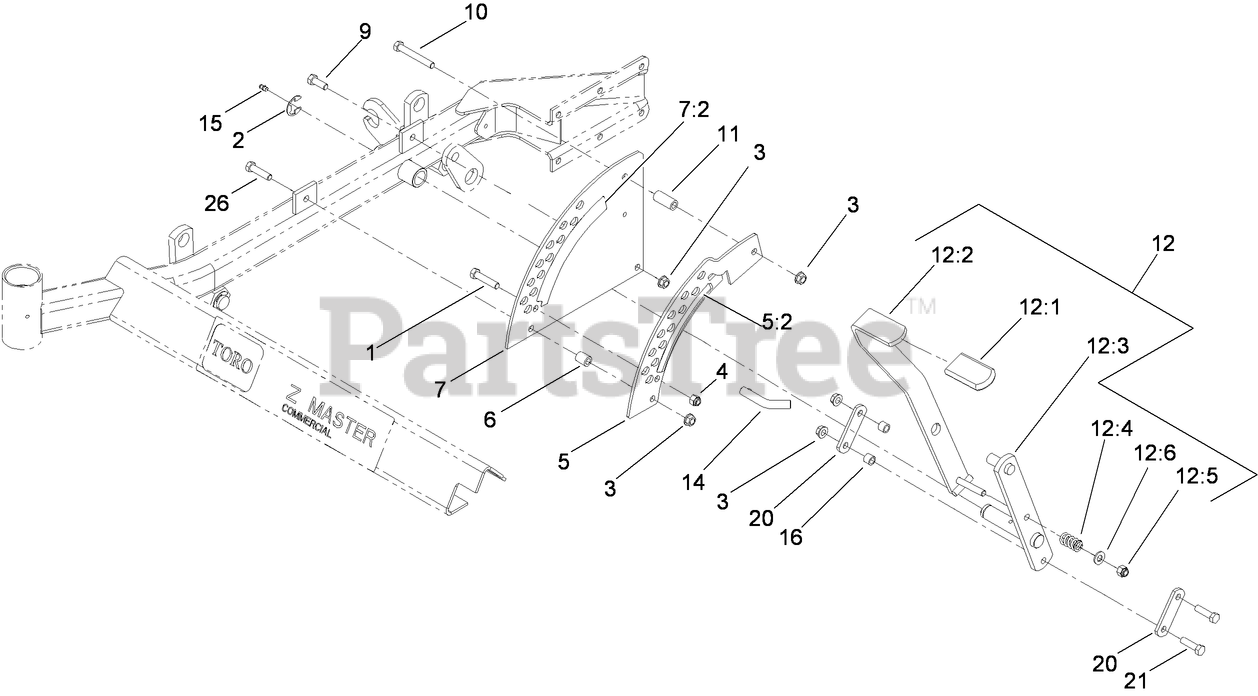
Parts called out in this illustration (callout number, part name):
1	SCREW-HH
2	RING-RETAINING, EXT
3	NUT-HHF, WHIZ
4	NUT-LOCK, NI
5	PLATE-HOC, INNER
5:2	DECAL-DECK HEIGHT, INNER
6	BUSHING-LEVER, LIFT
7	PLATE-HOC, OUTER
7:2	DECAL-DECK HEIGHT, OUTER
9	SCREW-HH
10	SCREW-HH
11	BUSHING-LEVER, LIFT
12	DECK LIFT HANDLE ASM
12:1	GRIP-LEVER, LIFT
12:2	HANDLE-LIFT
12:3	LIFT ARM ASM
12:4	SPRING-COMPRESSION
12:5	NUT-LOCK, NI
12:6	WASHER-FLAT
14	PIN-HOC
15	FITTING-GREASE
16	Bushing
20	ARM-LIFT, DECK
21	SCREW-HH
26	SCREW-HH
